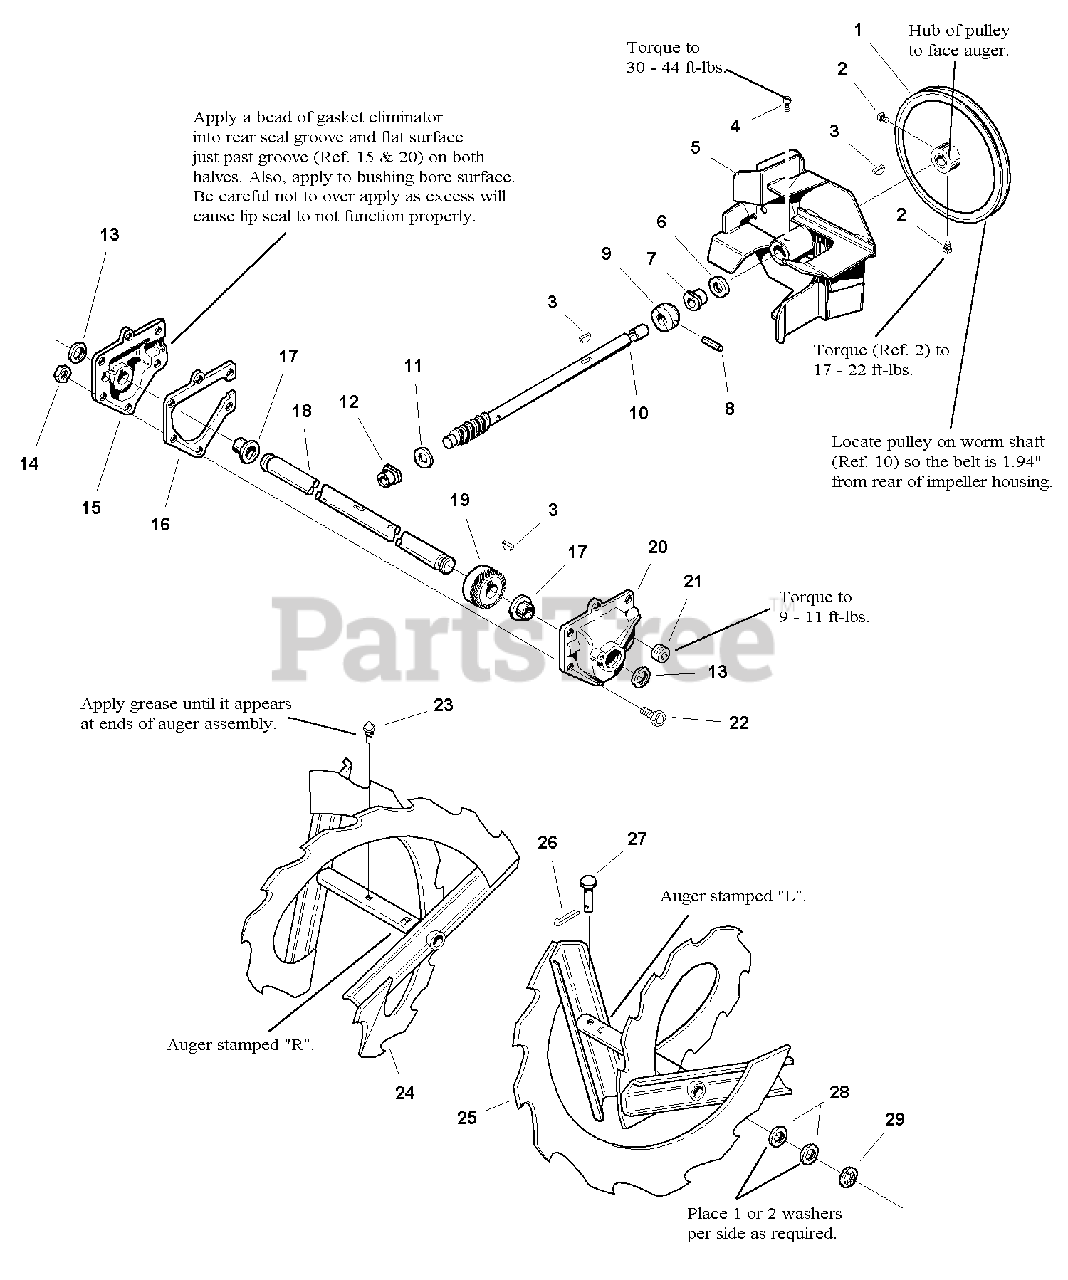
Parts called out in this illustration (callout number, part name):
1	PULLEY,Auger Drive
2	SETSCREW, Square Head Cup Point, 3/8-18 x 5/8
3	KEY, Woodruff 3/16 x 3/4
4	SETSCREW, Square Head Cup Point, 3/8-16 x 1/2
5	IMPELLER
8	PIN, Drive-Lock 3/16 x 1-1/2
9	THRUST COLLAR
10	SHAFT, Worm
11	WASHER, Thrust
14	NUT, Lock, 1/4-20
15	GEAR CASE COVER, R.H.
18	SHAFT, Auger
20	GEAR CASE COVER, L.H.
21	PIPE PLUG, 1/8 NPT
22	CAPSCREW, Hex Hd. 1/4-20 x 7/8
23	GREASE FITTING
24	AUGER, R.H. 22", Serrated
25	AUGER, L.H. 22", Serrated
26	PIN, Cotter 3/32 x 3/4
27	PIN, Shear
28	WASHER
29	RING, Retaining
